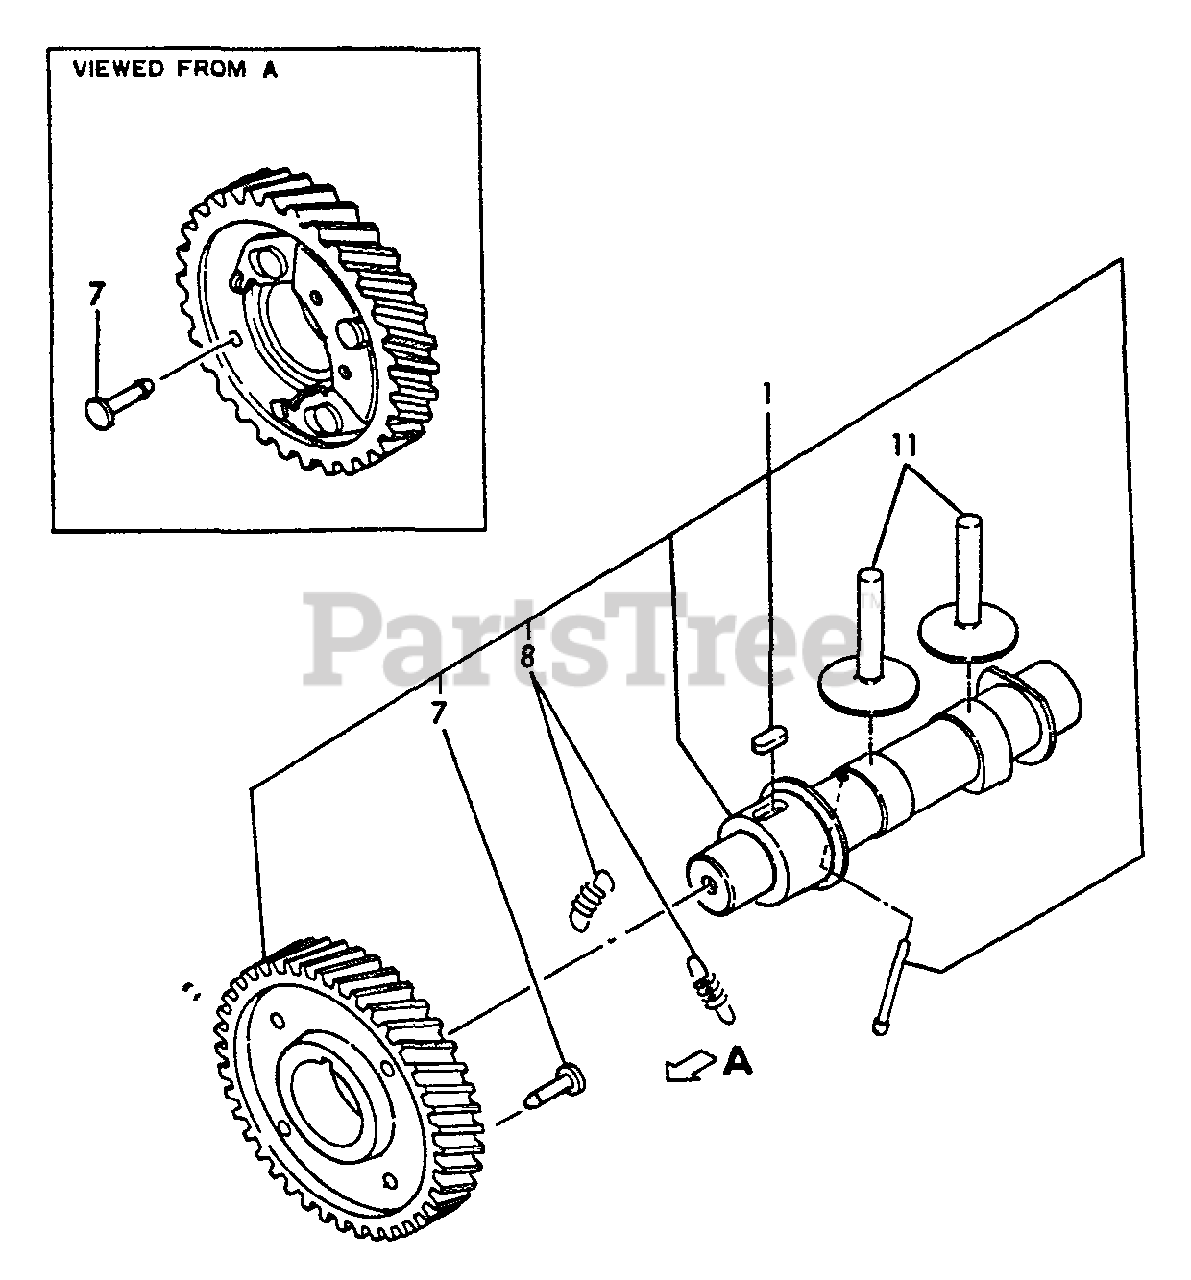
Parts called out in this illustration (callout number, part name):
1	CAMSHAFT ASSY
7	PIN (B), GUIDE
8	SPRING, DECOMP.
11	TAPPET
